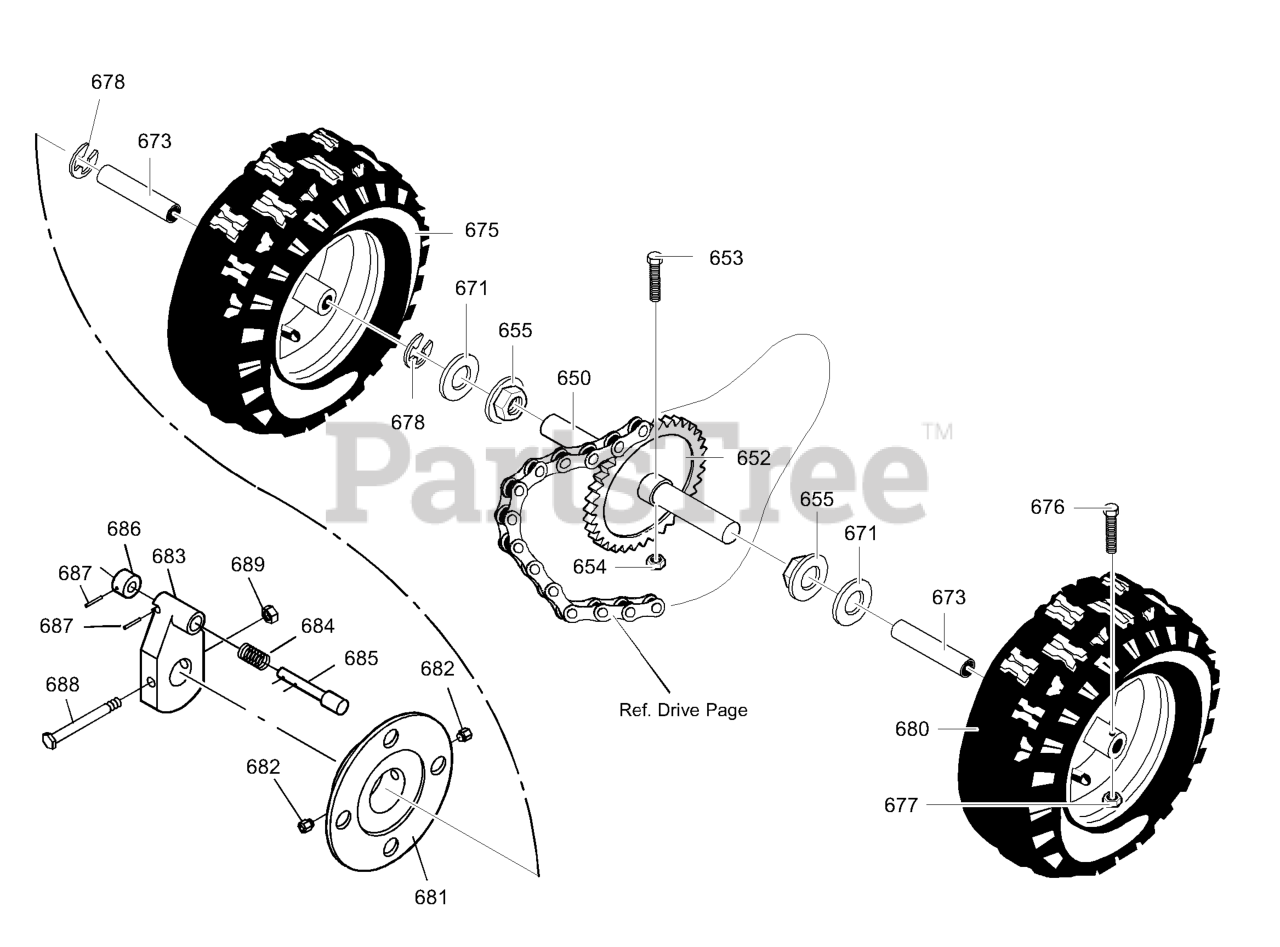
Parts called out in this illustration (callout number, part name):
650	SHAFT, AXLE
652	SPRKT & HUB
653	SCREW, 1/4-20X1.75
654	NUT, 1/4-20 HEX NYLOCK
655	BEARING, AXLE
671	FLATWASHER
673	BUSHING, WHEEL
675	TIRE & RIM, RIGHT
676	SCREW, 1/4-20X1.75
677	NUT, 1/4-20 HEX NYLOCK
678	RING, RET
680	TIRE & RIM, LEFT
681	DISC, WHEEL
683	HUB, WHEEL LOCK
684	SPRING, COMPRESSION
685	PIN, LOCK
689	NUT
